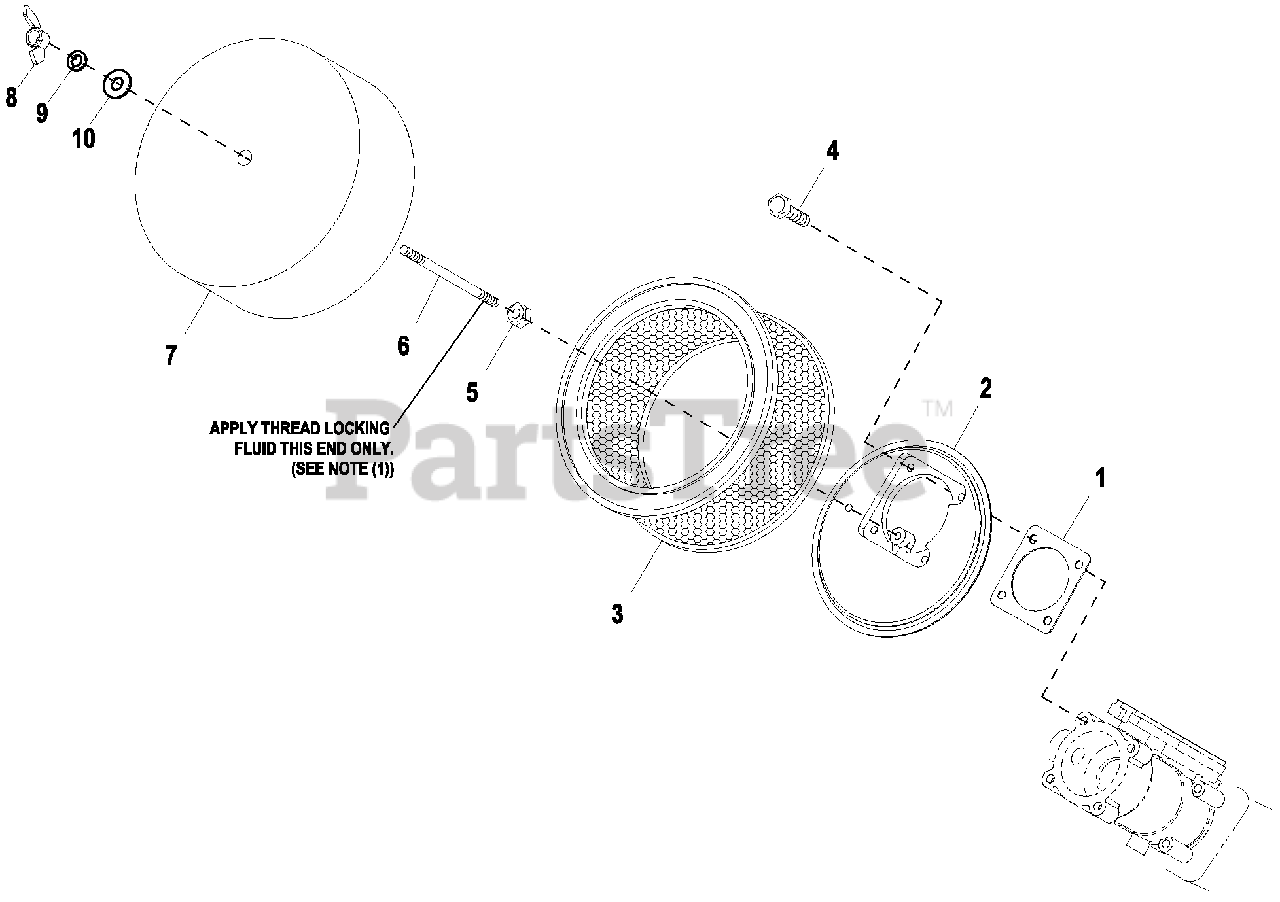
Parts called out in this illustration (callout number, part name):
1	GASKET BOSCH 32 & 40
2	ADAPTER CARBURETOR W/PVC CONN
3	ELE M ENT AIR CLEANER
4	SCREW HHC M5-0.8X16G8.8
5	NUT HEX 1/4-20 STEEL
6	STUD TH 1/4-20 X 4-1/2 G2 ZNC
7	PLATE, AIR CLEANER TOP 2.4L
8	NUT WING 1/4-20
9	WASHERLOCK M6-1/4
10	WASHER FLAT 1/4-M6 ZINC
